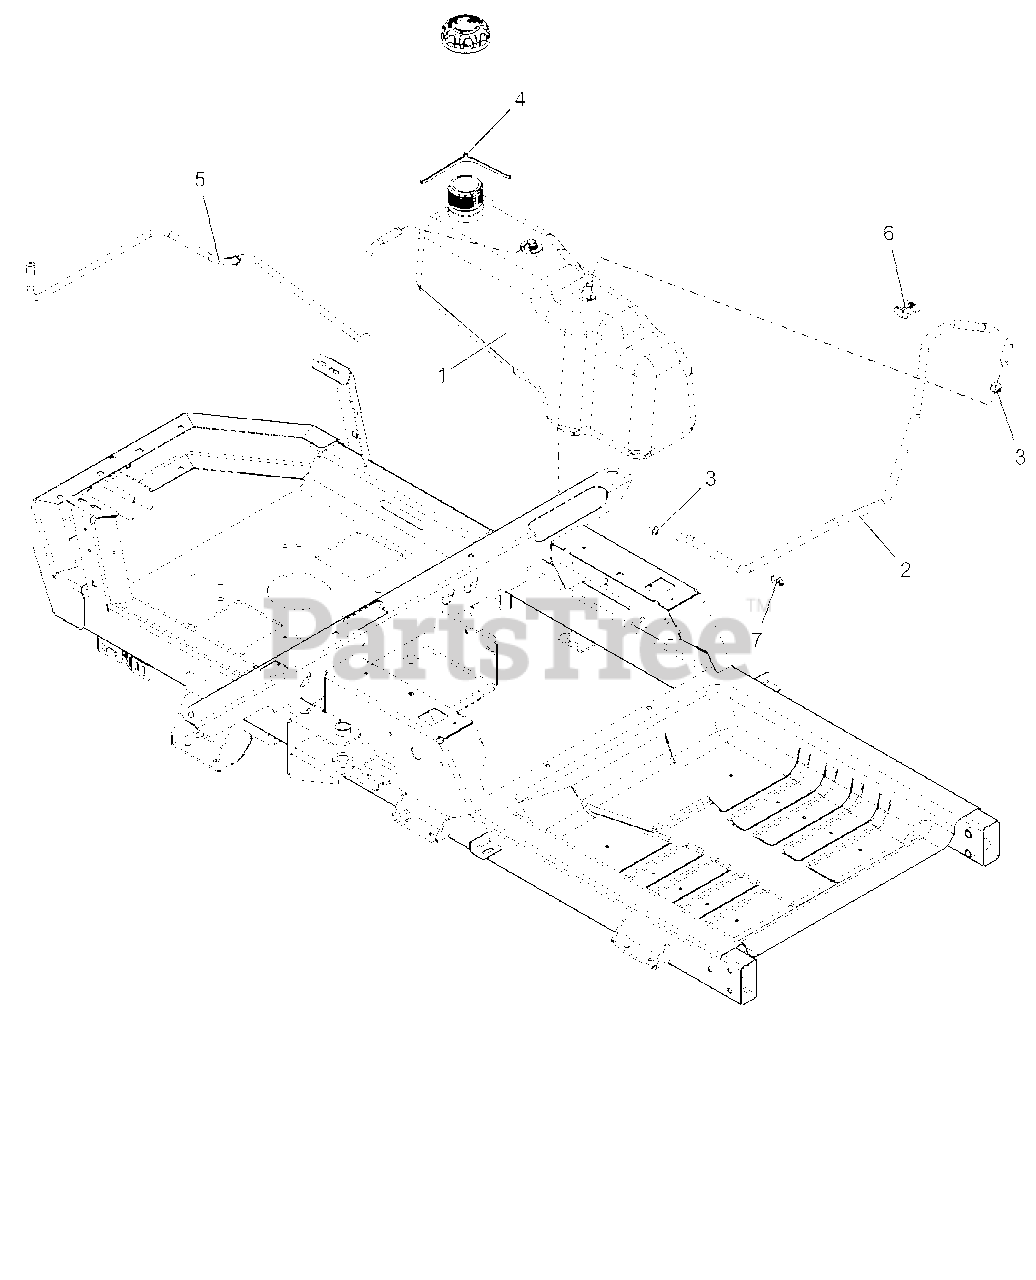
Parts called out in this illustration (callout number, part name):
1	ASM, TANK NON-PERM FUEL
2	HOSE, .25 LOW-PERM BULK GAS-35" LONG
3	CLAMP, FUEL LINE
4	CAP, FUEL VENT-IN 2.25" RATCHET
5	LINE, FUEL VENT KOHLER SMCHOKE
6	CLIP, T, .38-.50
7	CLIP, ROUTING (.50 ID)
